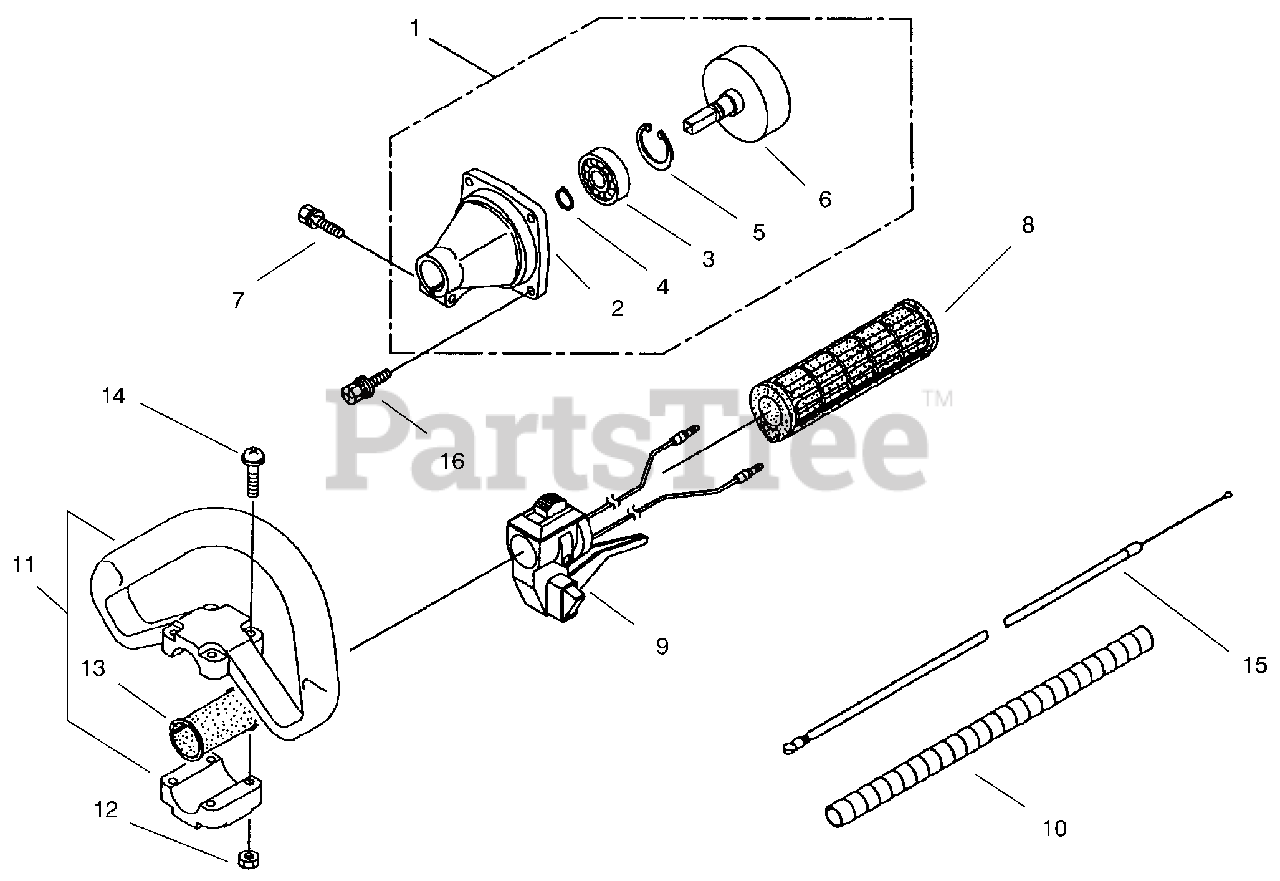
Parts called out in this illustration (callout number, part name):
1	Clutch Case Asm (Incl. Ref. # 2-6)
2	Clutch Case
4	Snap Ring
5	Snap Ring
6	Clutch Drum
8	Grip-Shaft
9	Trigger-Throttle
10	Tube-Plastic
11	Handle-Loop
15	Cable-Throttle
